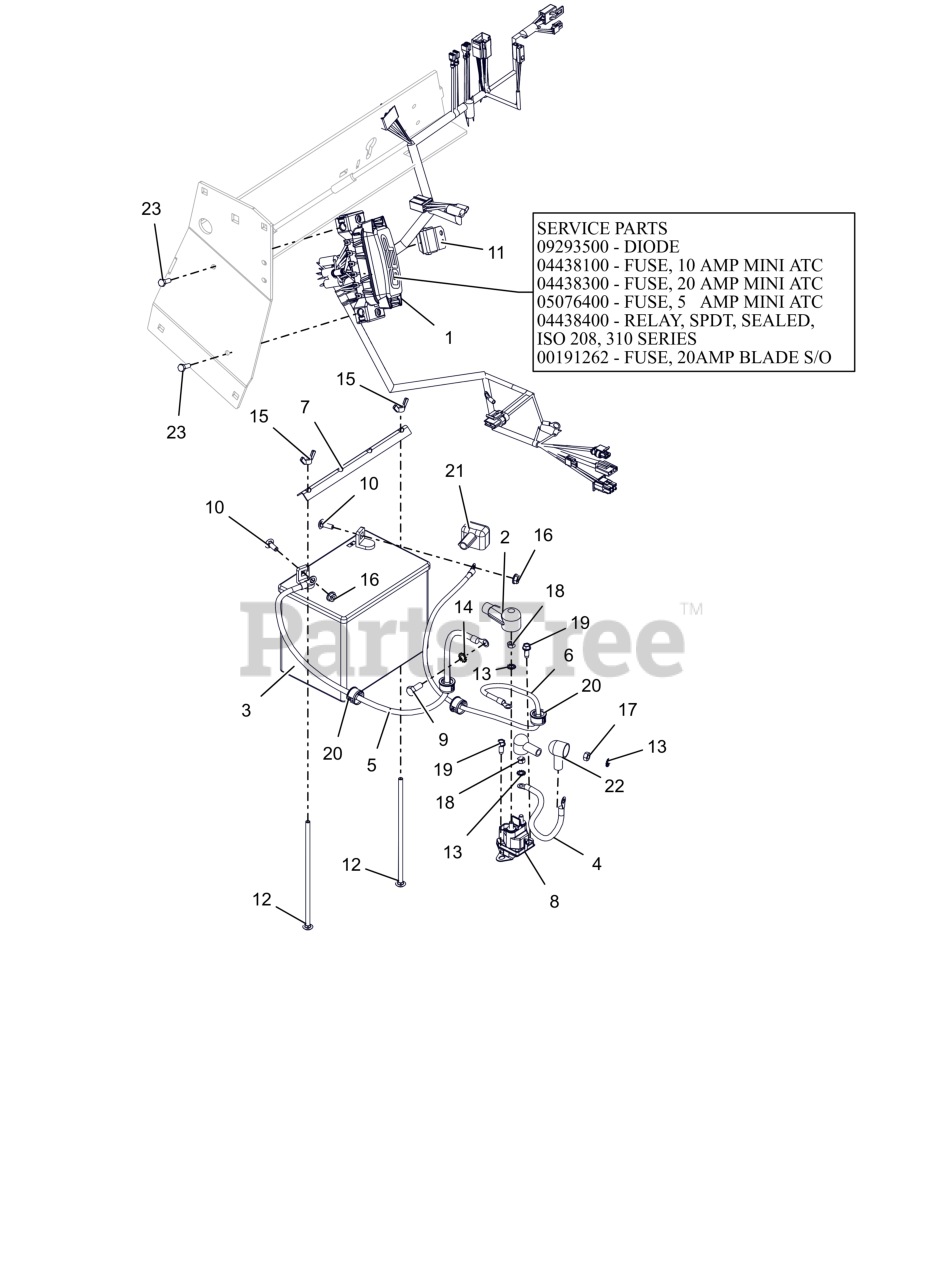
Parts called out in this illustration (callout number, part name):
1	HARNESS, PROSTANCE
1	DIODE, CONNECTOR SHELL
1	FUSE,10 AMP MINI-ATC
1	FUSE,20 AMP MINI ATC
1	FUSE, 5 AMP MINI-ATC
1	RELAY,MICRO5 TERML W/RESISTOR
1	FUSE, 20 AMP BLADE S/O
2	BOOT, BATTERY TERMINAL-RED
3	BATTERY, 300 CCA 10U1L
4	CABLE-POSITIVE BATTERY 9.00"
5	CABLE-NEGATIVE BATTERY 24.00"
6	CABLE-POSITIVE BATTERY 26.00"
7	HOLD DOWN
8	SOLENOID, STARTER (SEALED)
9	BLT, HEX M8-1.25X20 G8.8 ZCC
10	BLT, RHSN .25-20X.750 G5 ZCC
11	MODULE,INTERLOCK,DELAY, 1801
12	BTL,RHSN .250-20 X 7.5 G5 ZCC
13	WSHR,LK-EXT.262X.502X.026 ZCC
14	WSHR-LK-EXT 0.326X0.599X0.031 ZCC
15	NUT, LK-WING .25-20 ZCC
16	NUT-SPNLK-FLG .25-20 ZC120
17	NUT-STD .250-20 G2 ZCC
18	NUT-STD M6-1.0 ZCC
19	SCR,TAP .25-20X.625 HWH ZCC
20	BUSH, PANEL SNAP .687X.875X.56
21	INSULATOR
22	BOOT, EYELET TERMINAL
23	BLT, HEX M6-1.0 X 20 G8.8 ZCC
